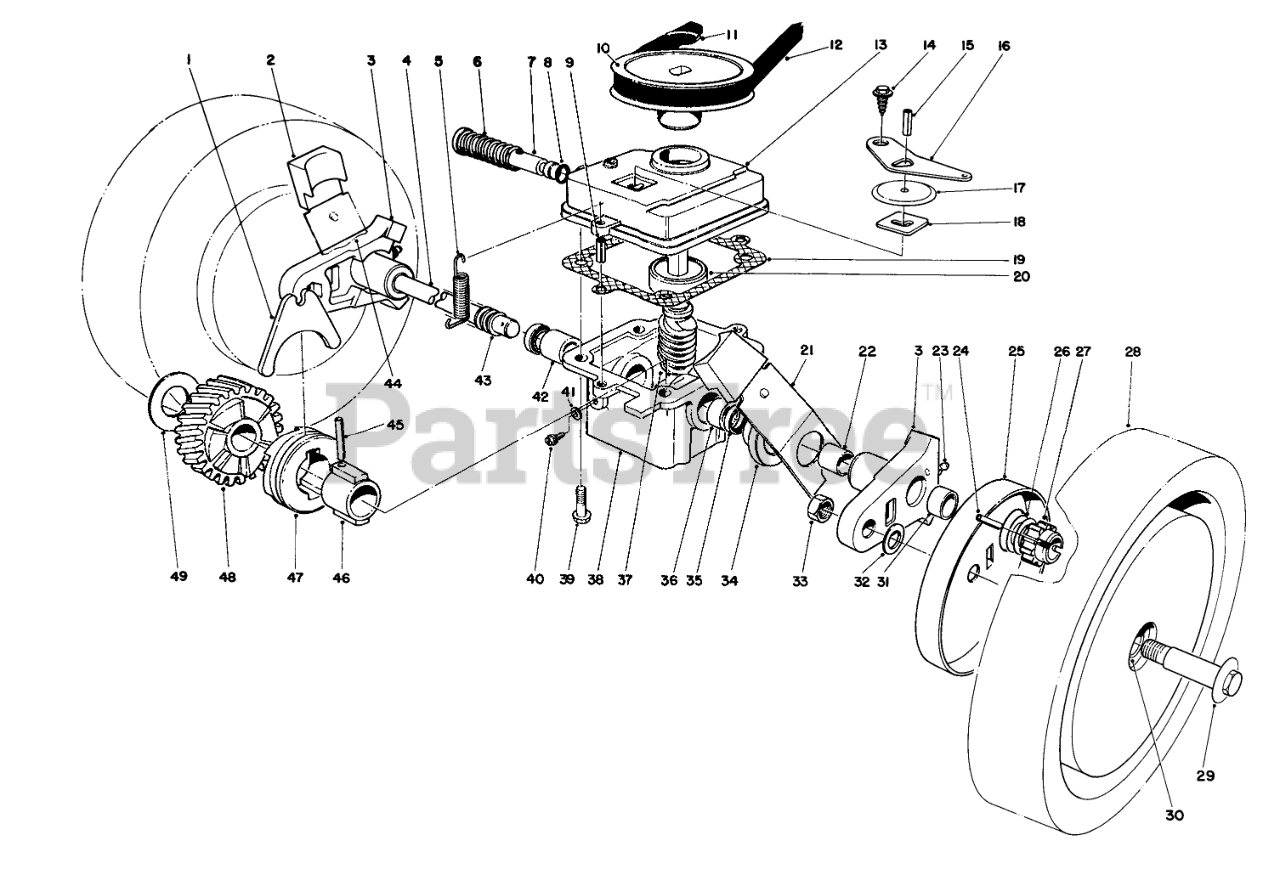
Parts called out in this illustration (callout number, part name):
1	SHIFTER FORK
2	KNOB-ARM
3	Pivot Arm (Incl. Ref. #22, 23&31)
4	DRIVE SHAFT (SERVCE)
5	TENSION SPRING
6	SPRING
7	SHIFTER ROD
8	O-RING
9	3/16 X 1/2 ROLL PIN
10	PULLEY
11	PUSH-ON 93-3236
12	V BELT
13	Case-Upper
14	Screw
15	PIN-ROLL
16	SHIFTER ARM
17	TRANS DUST COVER
18	LATCH PLATE
19	GASKET
20	BEARING
21	SPRING ARM ASM SP LH
22	BUSHING
23	FITTING-GREASE
24	Pin
25	WHEEL COVER
26	THRUST WASHER
27	PINION GEAR 14T
28	Wheel & Tire Assembly (Incl. Ref. #30)
29	BOLT-WHEEL
30	BUSHING
31	BUSHING
32	WASHER
33	Nut
34	End Cap
35	SEAL-OIL
36	BUSHING
37	Worm Shaft & Gear (Incl . Ref. #48)
38	Gear Case (Incl. Ref. #35-36 & 42)
39	Screw
40	NYLON SCREW
41	FILL PLUG GASKET
42	BUSHING
43	COVER-SHAFT, DRIVE
44	SPRING ARM ASM SP RH
45	COIL PIN
46	SLEEVE
47	CLUTCH JAW
48	Helical Gear
49	THRUST WASHER
